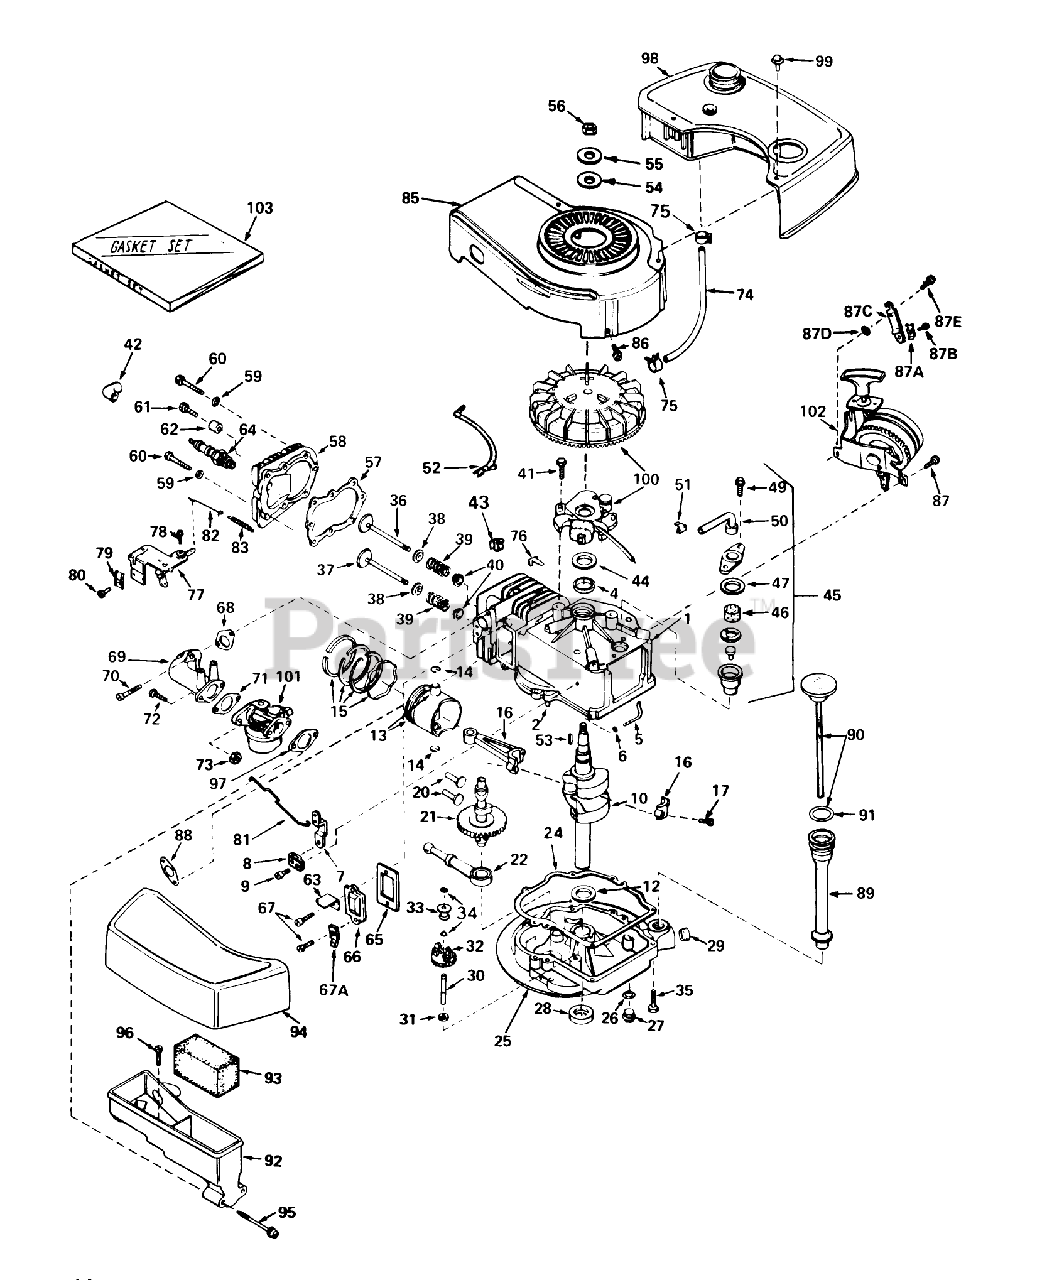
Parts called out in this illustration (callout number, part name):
1	Cylinder Assembly (Incl. Nos. 2, 4 87)
2	Pin-Dowel
4	Seal-Oil
5	Rod, Governor (Incl. No. 36)
6	Washer-Flat
7	Governor Lever
8	Clamp-Lever, Governor
9	Screw
10	Crankshaft
12	Washer-Thrust
13	Piston Pin Assembly (Incl. 2 of No. 14)(Std.)
13	Piston Pin Assembly (Incl. 2 of No. 14)(.010 Oversize)
13	Piston Pin Assembly (Incl. 2 of No. 14)(.020 Oversize)
14	Ring-Retaining, Piston Pin
15	Ring Set-Piston Std.
15	Ring Set-Piston .010 oversize
15	Ring Set-Piston .020 oversize
16	Rod Assembly, Connecting (Incl. Nos. 17 18)
17	Bolt-Rod, Connecting
20	Lifter-Valve
21	Camshaft(Mech.Comp. Release)
22	Oil Pump ASM
24	Gasket, Mounting
25	Flange Assembly, Mounting (Incl. #27, 28, 29 30)
26	Gasket-Oil Drain
27	Plug Oil Drain
28	Seal-Oil
29	Plug Oil Drain
30	Shaft-Governor
31	Washer-Flat
32	Governor Gear ASM
33	Spool-Governor
34	Ring-Retaining
35	Screw (1/4-20 x 1-1/4)
36	Valve, Intake (Incl. Ref. #38, 39 40) (Std.)
36	Valve, Exhaust (1/32" Oversize) (Incl. Nos. 8, 9 10)
37	Valve, Exhaust (Standard) (Incl. Nos. 8, 9 10)
37	Valve, Exhaust (1/32" Oversize) (Incl. Nos. 8, 9 10)
38	Cap-Upper Valve Spring
39	Spring-Valve
40	Cap-Valve, Spring
41	Screw
42	Cover-Spark Plug
43	Clip, Wire
44	Gasket Stator
45	Breather Assy. (Incl. Ref. #46, 47, 49, 50 51 )
46	Element-Breather
47	Gasket-Breather
49	Screw, Hex Hd. w/Conical
50	Tube, Breaker
51	Clip, Breather
52	Wire Ground
53	Key, Flywheel
54	Washer Flat
55	Washer-Spring
56	Hex Nut
57	Oil Fill Tube
58	Head Cylinder
59	Washer
60	Screw
61	Screw Hex Hd. Cap
62	Space
63	Retainer Clip
64	Plug, Spark (Champion RCJ-8)
65	Gasket-Breather
66	Cover-Valve
67	Screw
67A	Terminal
68	Gasket, Intake
69	Pipe, Intake
70	Screw (1/4-20 x 1)
71	Gasket-Carburetor
73	Nut and Lock Washer (1/4-28)
74	Line-Fuel
75	Clamp-Line, Fuel
76	Clip-Wire
77	Control Assy., Speed (Incl. Nos, 76, 78 89)
78	Screw (10-24 x 3/4)
79	Conduit
80	Screw (10-32 x 3/8)
81	Link Governor
82	Link Governor Spring
83	Spring Governor
85	Housing, Blower
86	Screw
87	Screw (1/4-20 x 1/2)
87A	Conduit
87B	Screw (10-32 x 3/8)
87C	Bracker
87D	Washer
87E	Screw (1/4-20 X 5/8)
88	Gasket Exhaust
89	Tube Fill
90	Dipstick, Oil (Incl. Ref. #101)(Twist Lock)
91	O-Ring
92	Body Air Cleaner
93	Filer, Air
94	Cove, Air Cleaner
95	Screw Fil Hd.
96	Screw, Hex Hd.
97	Gasket-Air Cleaner
98	Tank Fuel
99	Screw (10-32 x 35/64)
100	Magneto
101	Carburetor
102	Starter
103	53024/VAR.16HP O/P
